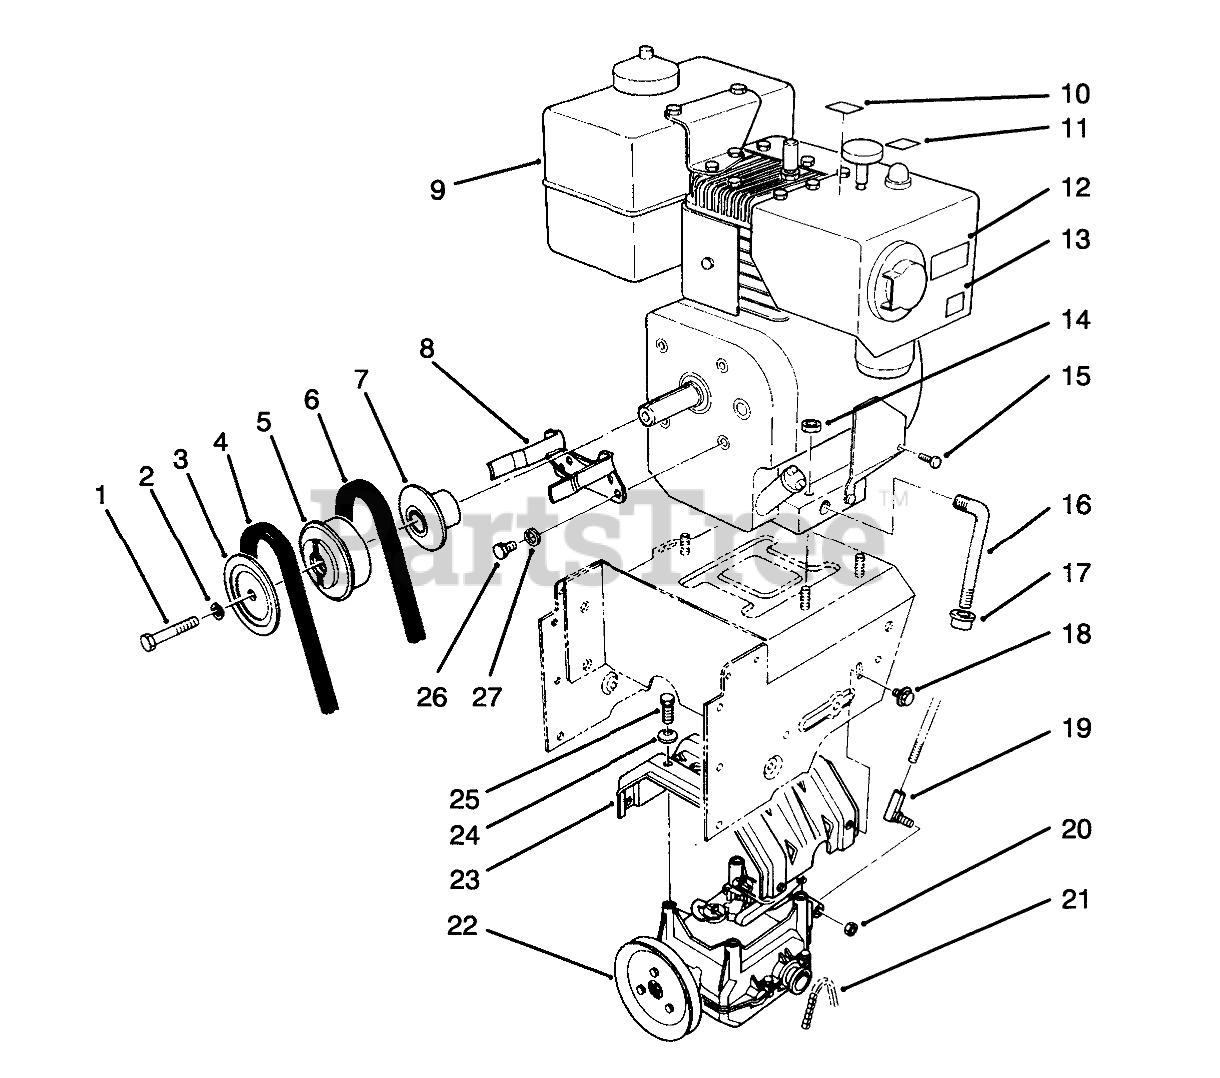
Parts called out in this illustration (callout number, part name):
1	SCREW-HH
2	WASHER-LOCK
3	SHEAVE-HALF, IMPELLER
4	V-BELT, IMPELLER
5	PULLEY-ENGINE, CENTER
6	V-BELT, TRACTION
7	SHEAVE-HALF, TRACTION
8	Guide-Belt
9	Engine-Briggs & Stratton
10	DECAL - THROTTLE, INT'L
11	DECAL - PRIMER, INT'L
12	DECAL-WARNING, HOT SURFACE
13	DECAL - CHOKE
14	NUT-HF
15	SCREW-HH
16	8 HP DRAIN TUBE
17	CAP-PIPE
18	SCREW-HHF
19	JOINT-BALL
20	NUT-LOCK, NI
21	CHAIN
22	TRACTION GEARCASE ASM
23	Frame-Transmission
24	WASHER-SPRING
25	SCREW-HWHTF
26	SCREW-HH
27	WASHER-LOCK
